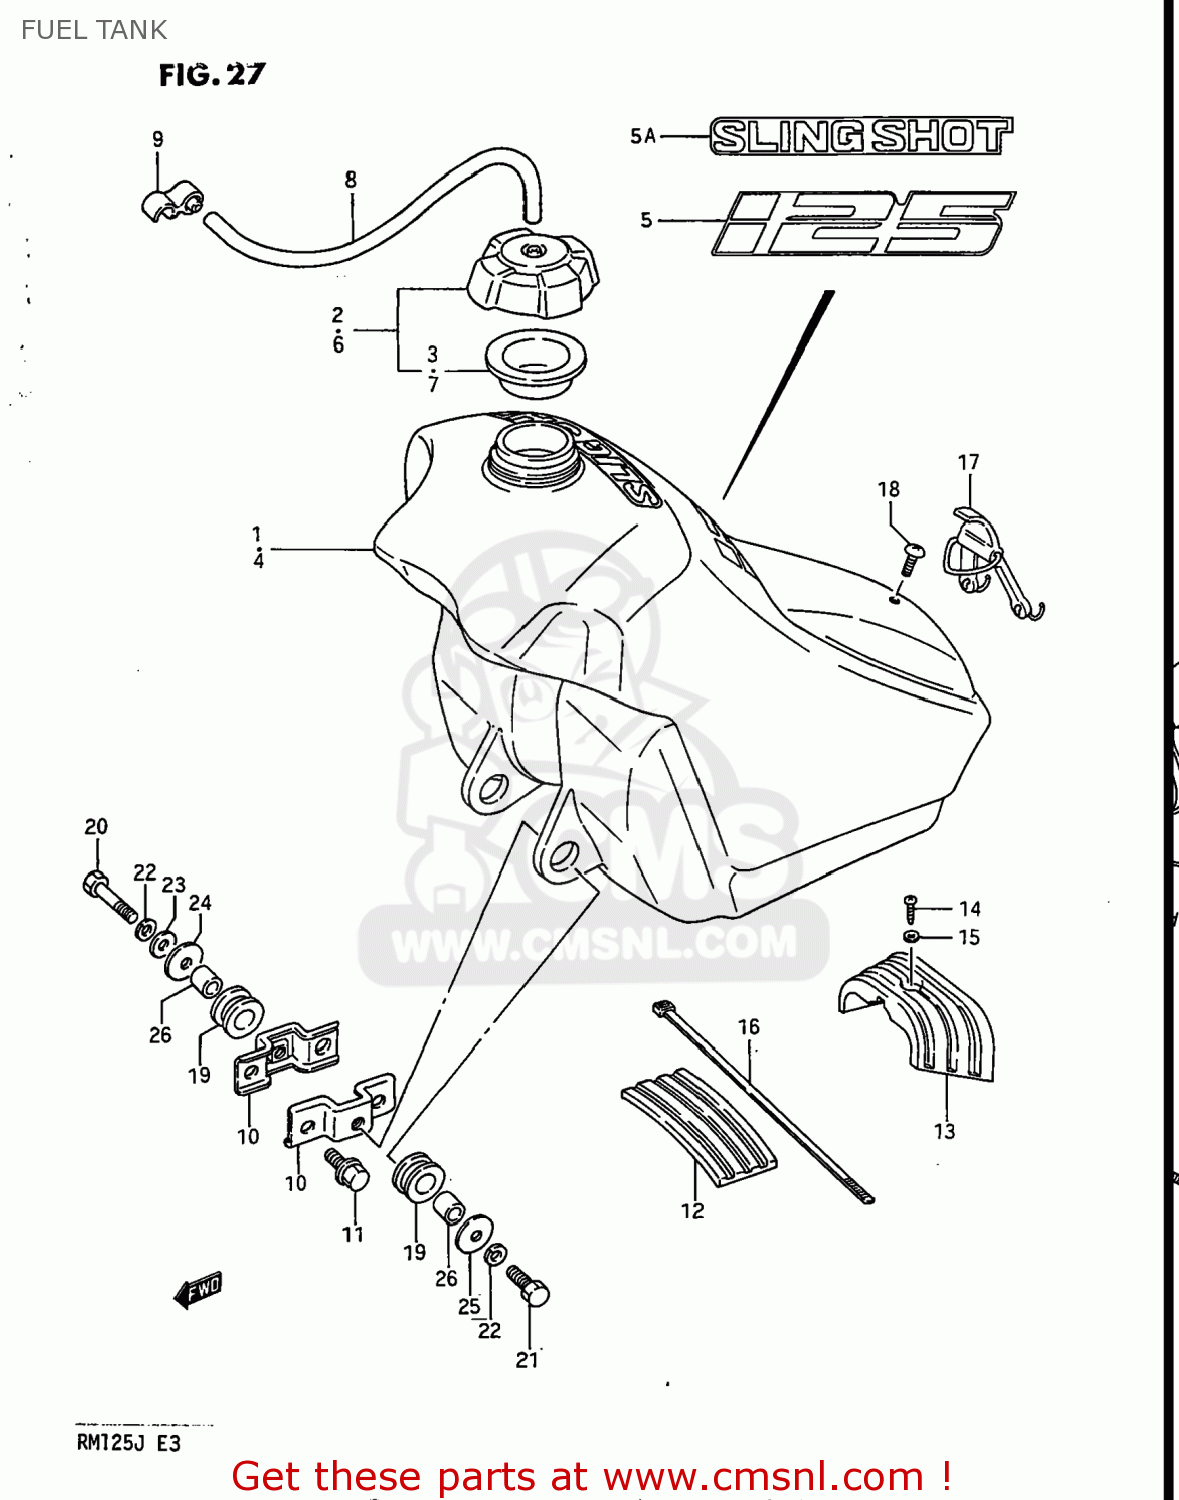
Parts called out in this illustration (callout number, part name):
1	TANK SET,FUEL
2	CAP SET,FUEL TANK
3	GASKET,FUEL TANK CAP (NAS)
4	TANK SET,FUEL
5	TAPE,FUEL TANK (125)
5A	EMBLEM
6	CAP SET,FUEL TANK
7	GASKET,FUEL TANK CAP (NAS)
8	HOSE
9	CLAMP,BREATHER HOSE
10	BRACKET,FUEL TANK
11	BOLT 8X16
12	CUSHION,FUEL TANK UPR FR
13	CUSHION,FUEL TANK,UPPER
14	SCREW
15	WASHER
16	CLAMP
17	BAND,FUEL TANK RR
18	SCREW
19	CUSHION
20	BOLT
21	BOLT
22	LOCK WASHER
23	WASHER
24	WASHER(8.5X26X1.2)
25	WASHER
26	SPACER(8.4X12X12)
